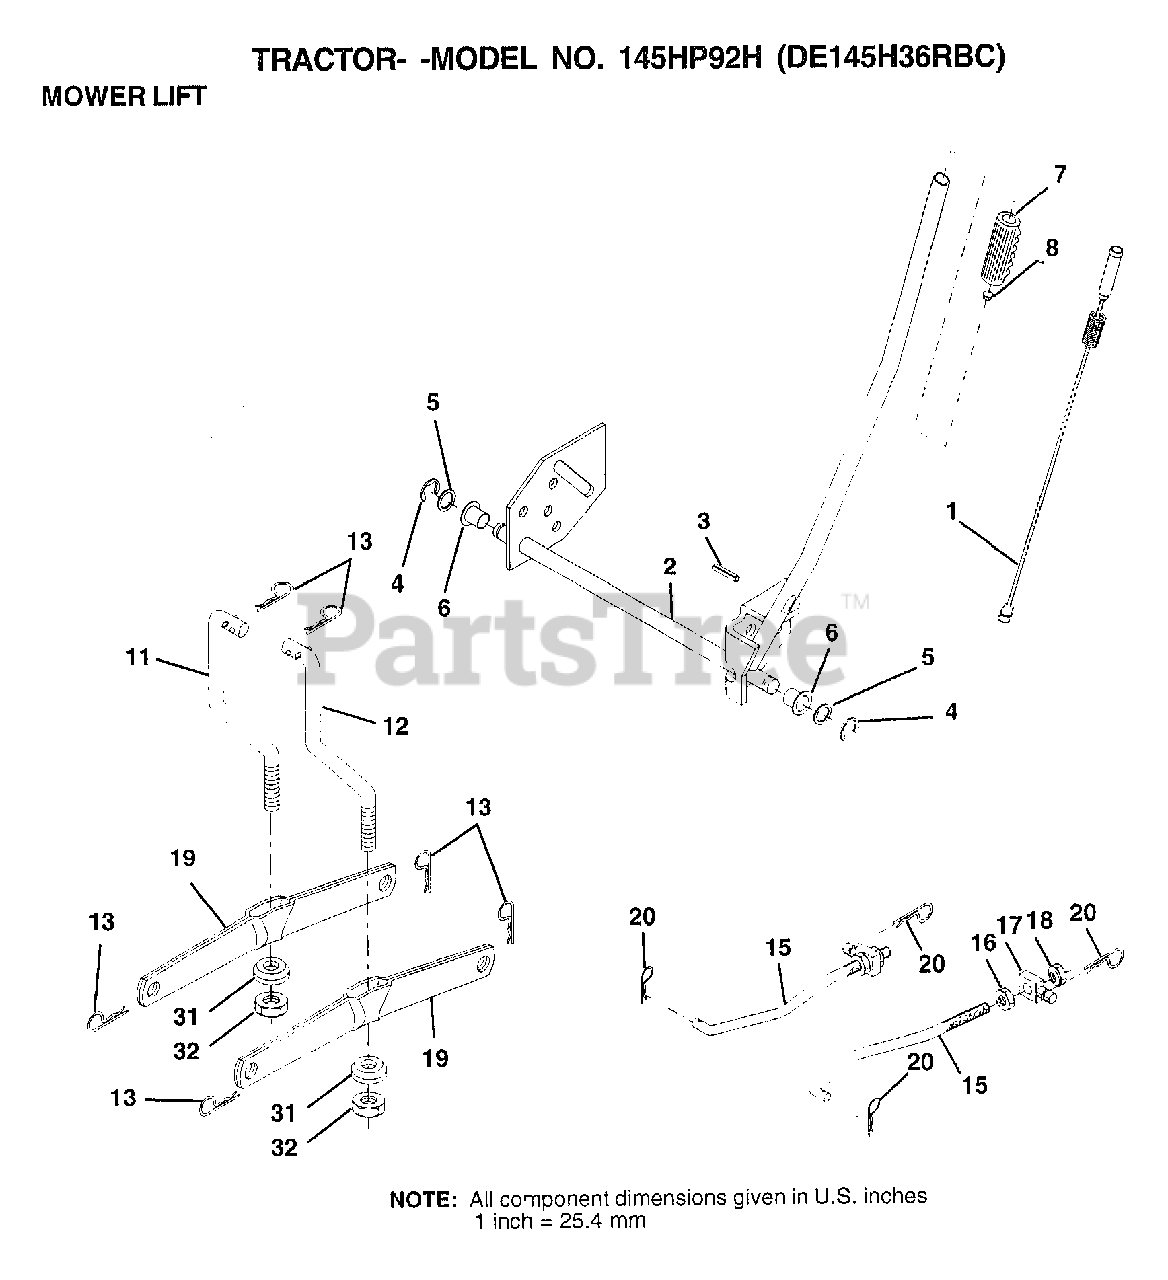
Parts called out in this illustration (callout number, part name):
1	WIRE ASM W.SPRING
2	"SHAFT ASM LIFT,RH"
3	PIN-GROOVE LT
5	WASHER
6	NYLON BEARING
7	GRIP
11	LINK.LIFT.LH.CRD
12	LINK.LIFT.RH.CRD
15	LINK, FRONT
16	NUT
17	TRUNION
18	NUT.LK.W/WSH.1/2.
19	ARM SUSP REAR
20	RETAINER SPRING
31	BEARING PVT LH
32	NUT.CROWNLOCK.3/8
